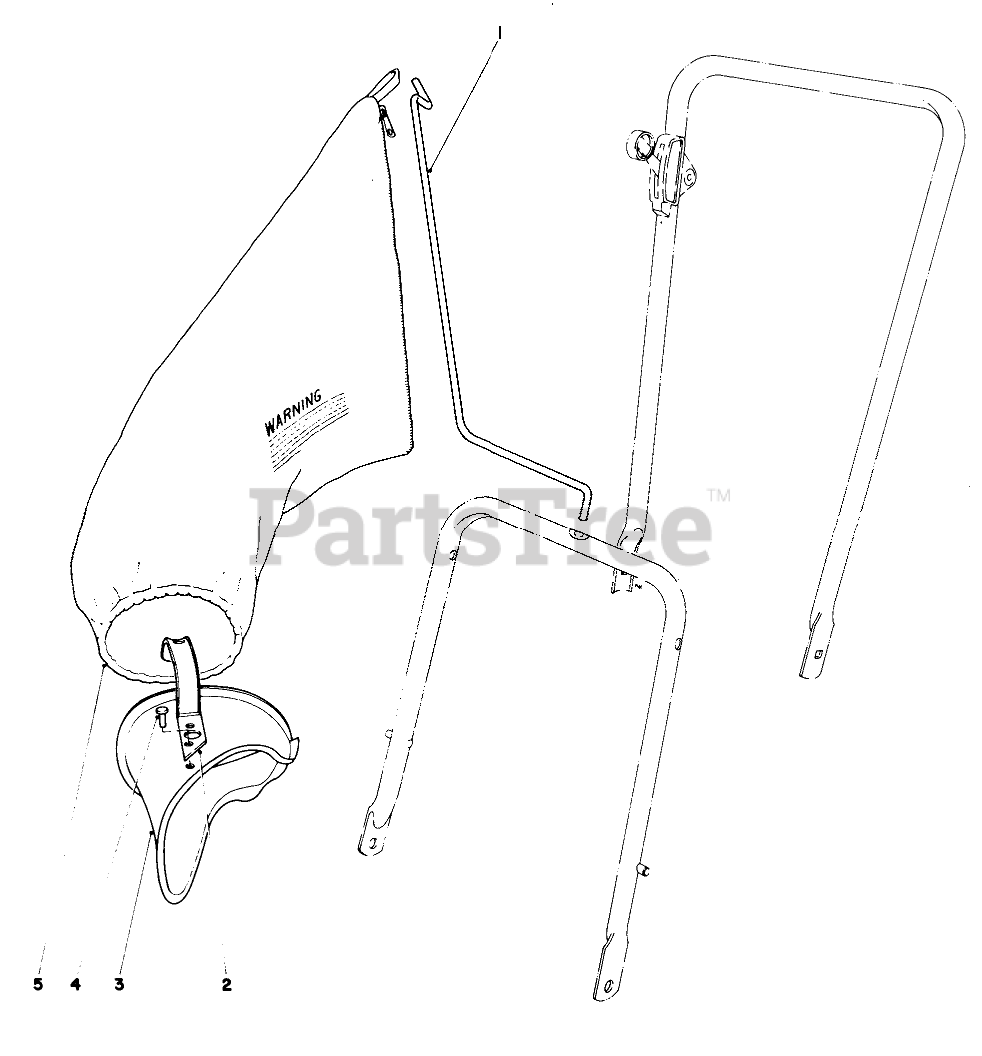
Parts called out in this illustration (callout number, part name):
1	BAG HANGER ROD
2	BAG CHUTE HANDLE
3	Grass Chute Assembly (Incl. Ref. #2 & 4)
4	RIVET 3/16 X 7/16
5	Grass Bag Assembly
